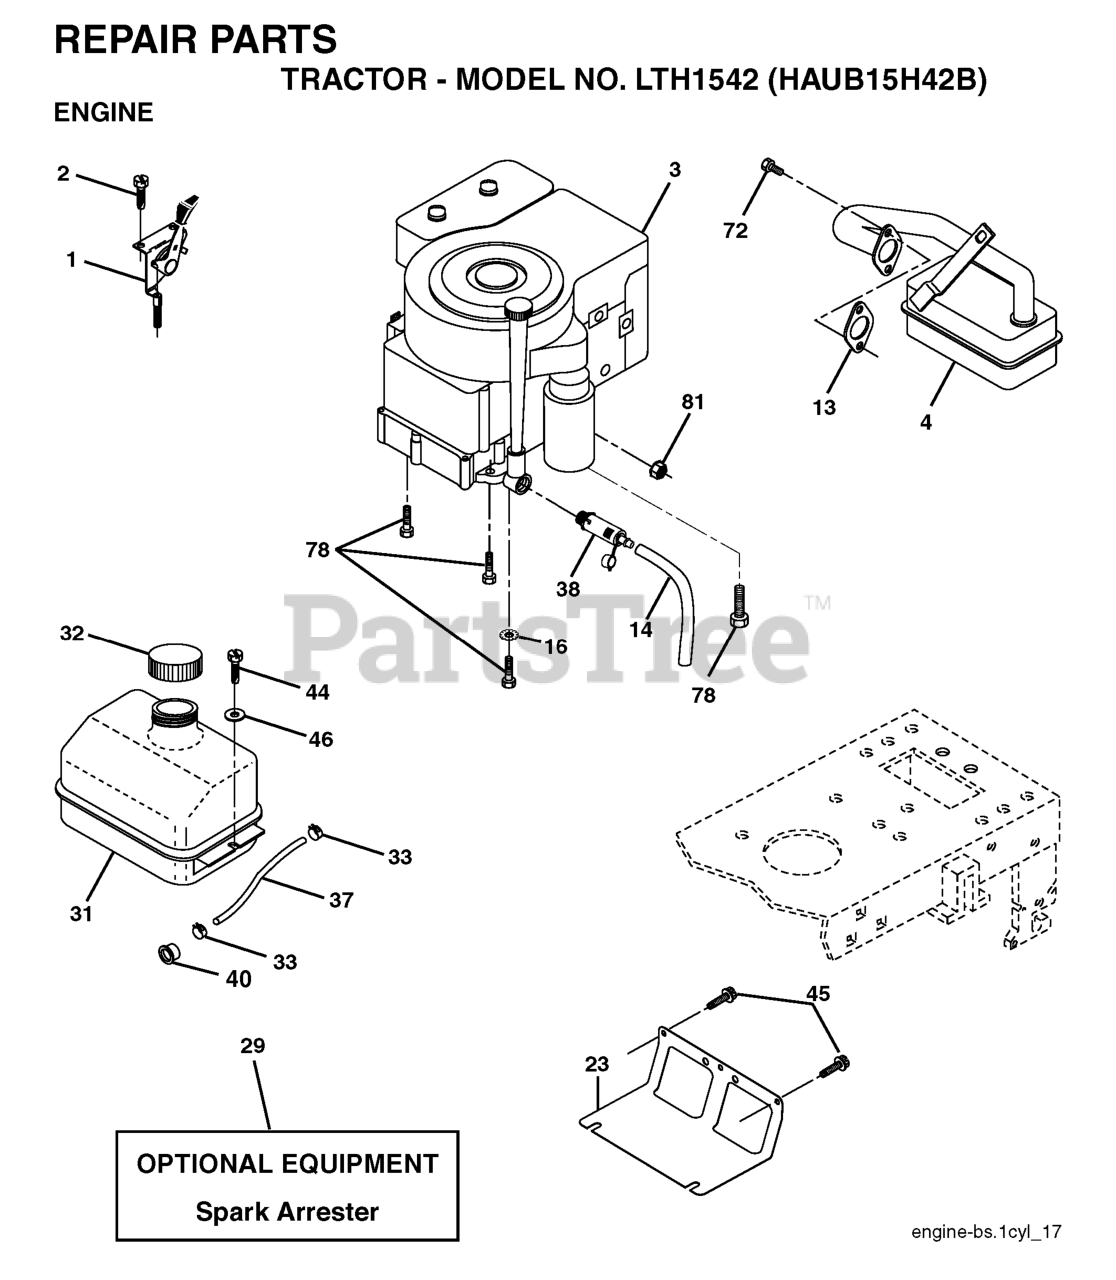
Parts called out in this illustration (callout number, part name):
1	CONTROL.THROTTLE/CHOKE.BLACK
2	SCREW
4	MUFFLER.LT.BRIGGS.14HP.IC/OHV
13	REPL BY 532 27 22-93
14	TUBE, DRAIN OIL ASM.
16	LOCKWASHER
23	SHIELD.BROWNING.DBR.GUARD
29	KIT.SPARK ARRESTOR 794945 B&S
31	TANK.ASM.FUEL.FRONT.W/CAP
32	FUEL CAP
33	HOSE CLAMP
37	LINE.FUEL.20
38	PLUG DRAIN OIL EASY
40	BUSHING.SNAP.NYL.BLK.
44	SCREW HEXWSHR 1/4-20X3/4
45	SCREW, 3/8-16X3/4
72	SCREW.SOCKET.HEAD.5/16-18
78	SCREW.3/8-16
81	NUT
